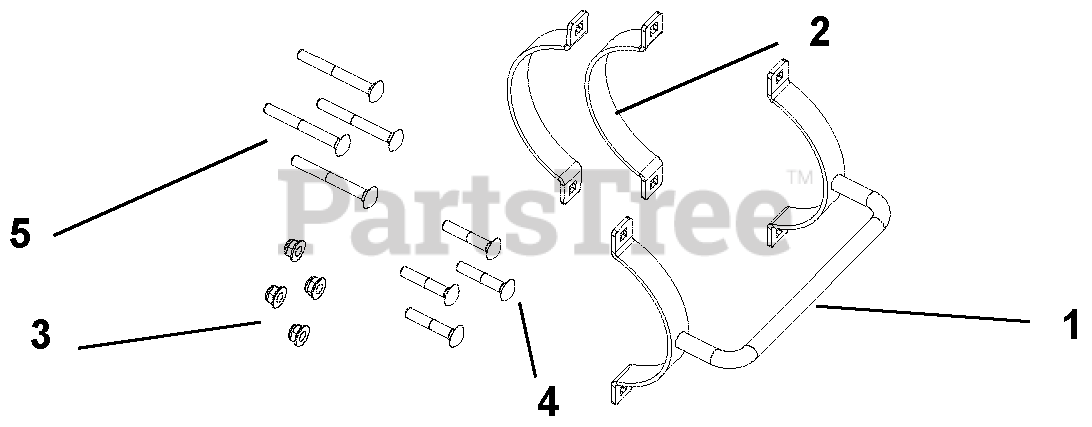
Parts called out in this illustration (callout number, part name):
1	WDMT, HYD. CYLINDER CLAMP
2	BRKT, CYLINDER CLAMP
3	@BLT-HEX .38-16X1.25 GR5 YWZC
4	BLT-RDHDSQNK .31-18X2.75 G5YZ
5	@BLT-RDHDSQNK .31-18X1.75 G5YZ
